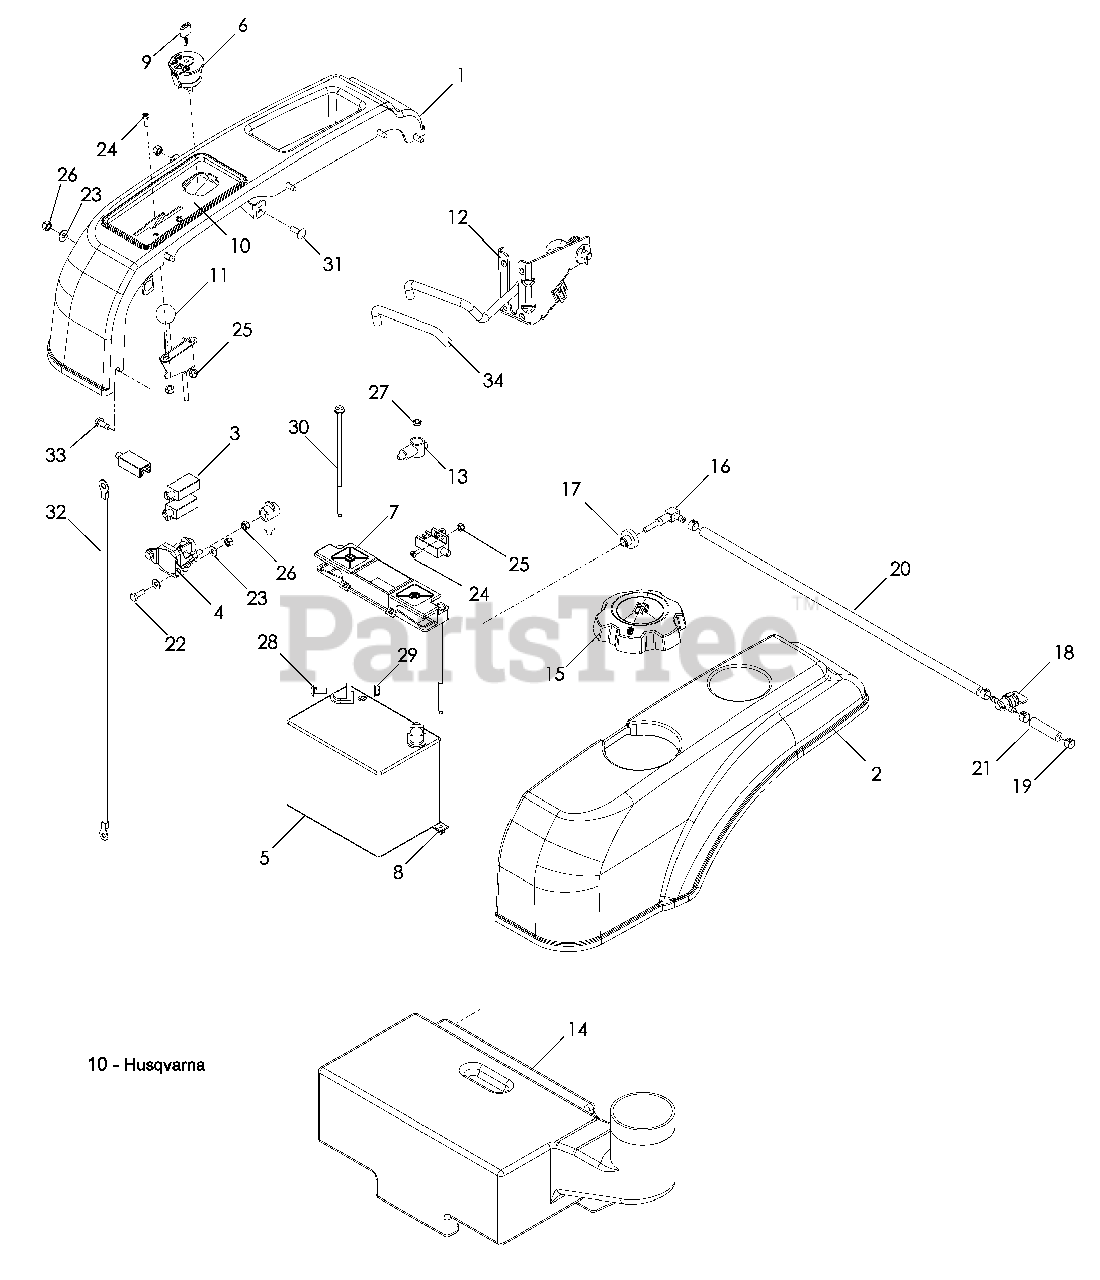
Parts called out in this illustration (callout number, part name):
1	FENDER, RH
2	FENDER, LH
5	BATTERY
6	SWITCH, IGNITION
7	BATTERY HOLD DOWN
8	NUT ¼ PUSH NYLON
9	KEY, IGNITION
10	PANEL, CONTROLS
11	CABLE, THROTTLE
12	CLUTCH ASSM w/ CABLE
13	TERMINAL COVER, SM
14	TANK, FUEL
16	ELBOW w/ FILTER
17	FITTING, TANK
18	VALVE, FUEL
19	CLAMP, HOSE
20	HOSE ¼ x 21
21	HOSE, ¼ x 2
22	HCS ¼-20 x ¾
23	WASHER ¼ FLAT SAE
24	SCREW #10-24 x 5/8
25	NUT #10-24 HEX NYLOC
26	NUT ¼-20 HEX NYLOC
27	NUT ¼-20 HEX THIN NYLOC
28	RHSNB 5/16-18 x ¾
29	NUT 5/16-18 FLANGE NYLOC
30	BOLT ¼ x 7½
31	RHSNB ¼-20 x ¾ GR2
32	BATTERY CABLE, NEGATIVE
33	SCREW ¼-20 x 5/8 SLF TAP
34	GRIP, CLUTCH
